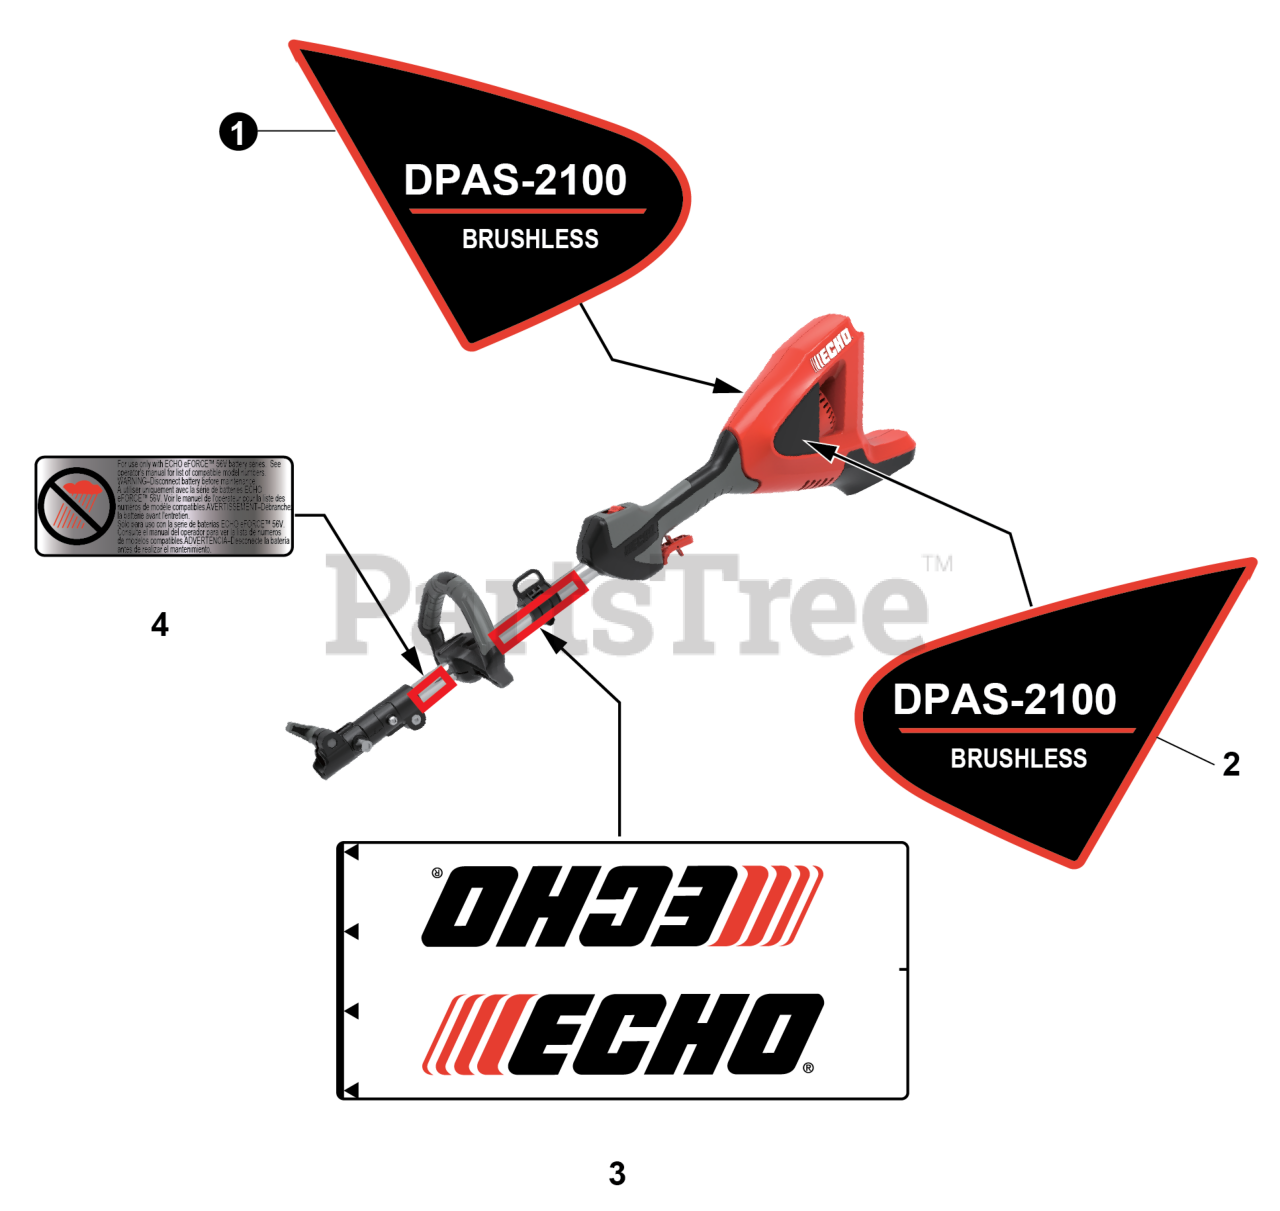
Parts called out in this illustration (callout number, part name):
1	LABEL,RIGHT HOUSING WITH MODEL NUMBER
2	LABEL,LEFT HOUSING WITH MODEL NUMBER
3	LABEL,MAIN PIPE
4	LABEL,RAIN
